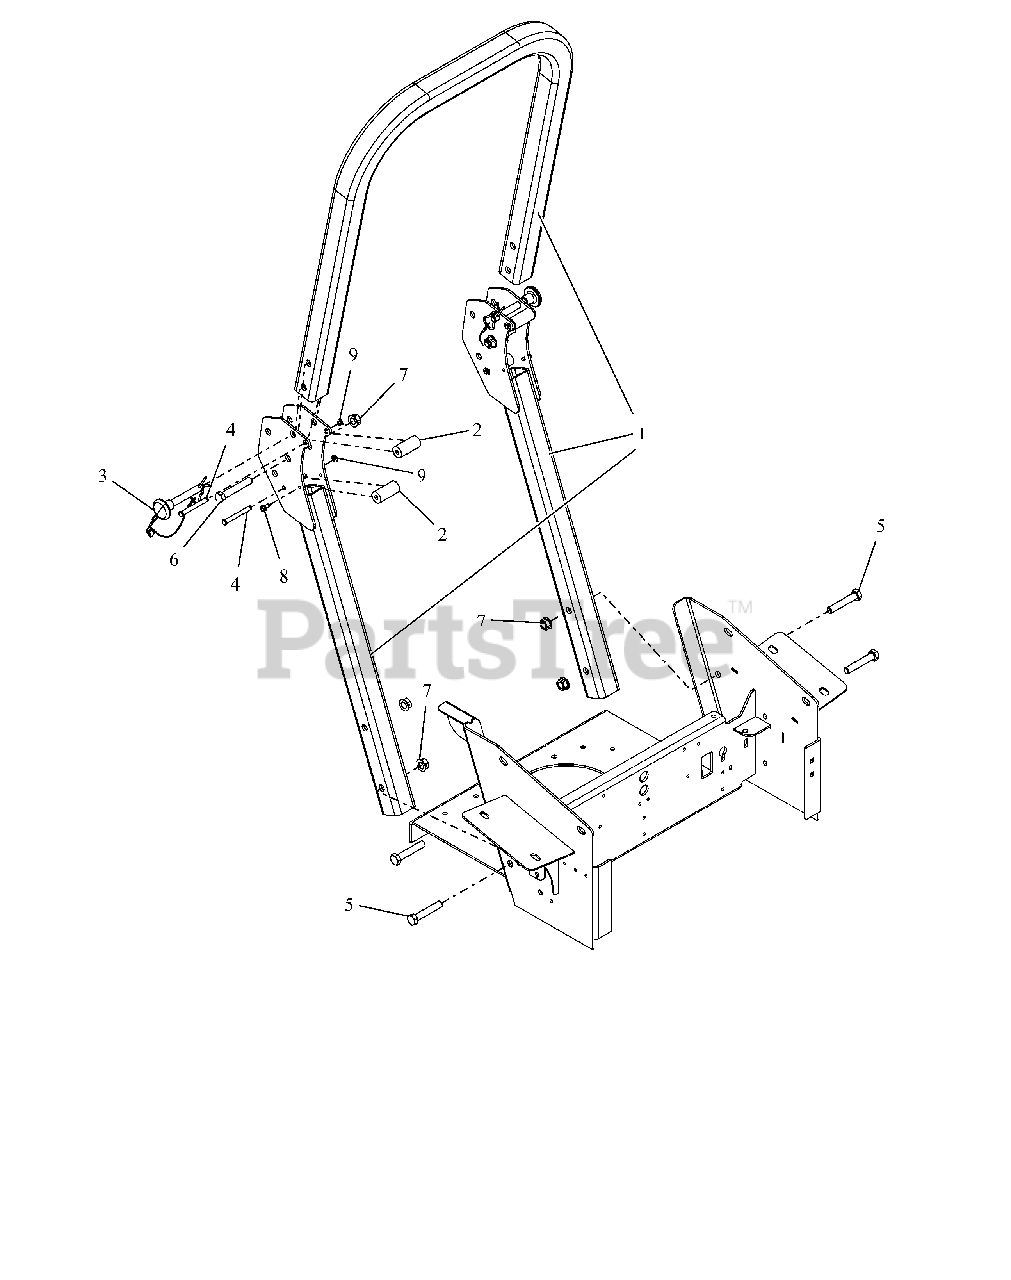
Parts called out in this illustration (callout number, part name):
1	ROPS, PT/PT100 REPLACEMENT
2	BUMPER, ROPS ANTI-VIBRATION
3	PIN, ROPS W/LANYARD
4	PIN, 5/16 X 2-9/16 WITH GROOVE
5	@BLT-HEX .50-13X2.75 GR5 YWZC
6	@BLT-HEX .50-13X3.00 GR5 YWZC
7	NUT-LK-CTR-FLG .50-13 YWZC
8	SCR-TAP .25-20X.50 HWH TR YWZ
9	RING, RETAINING-E .312 X .025
